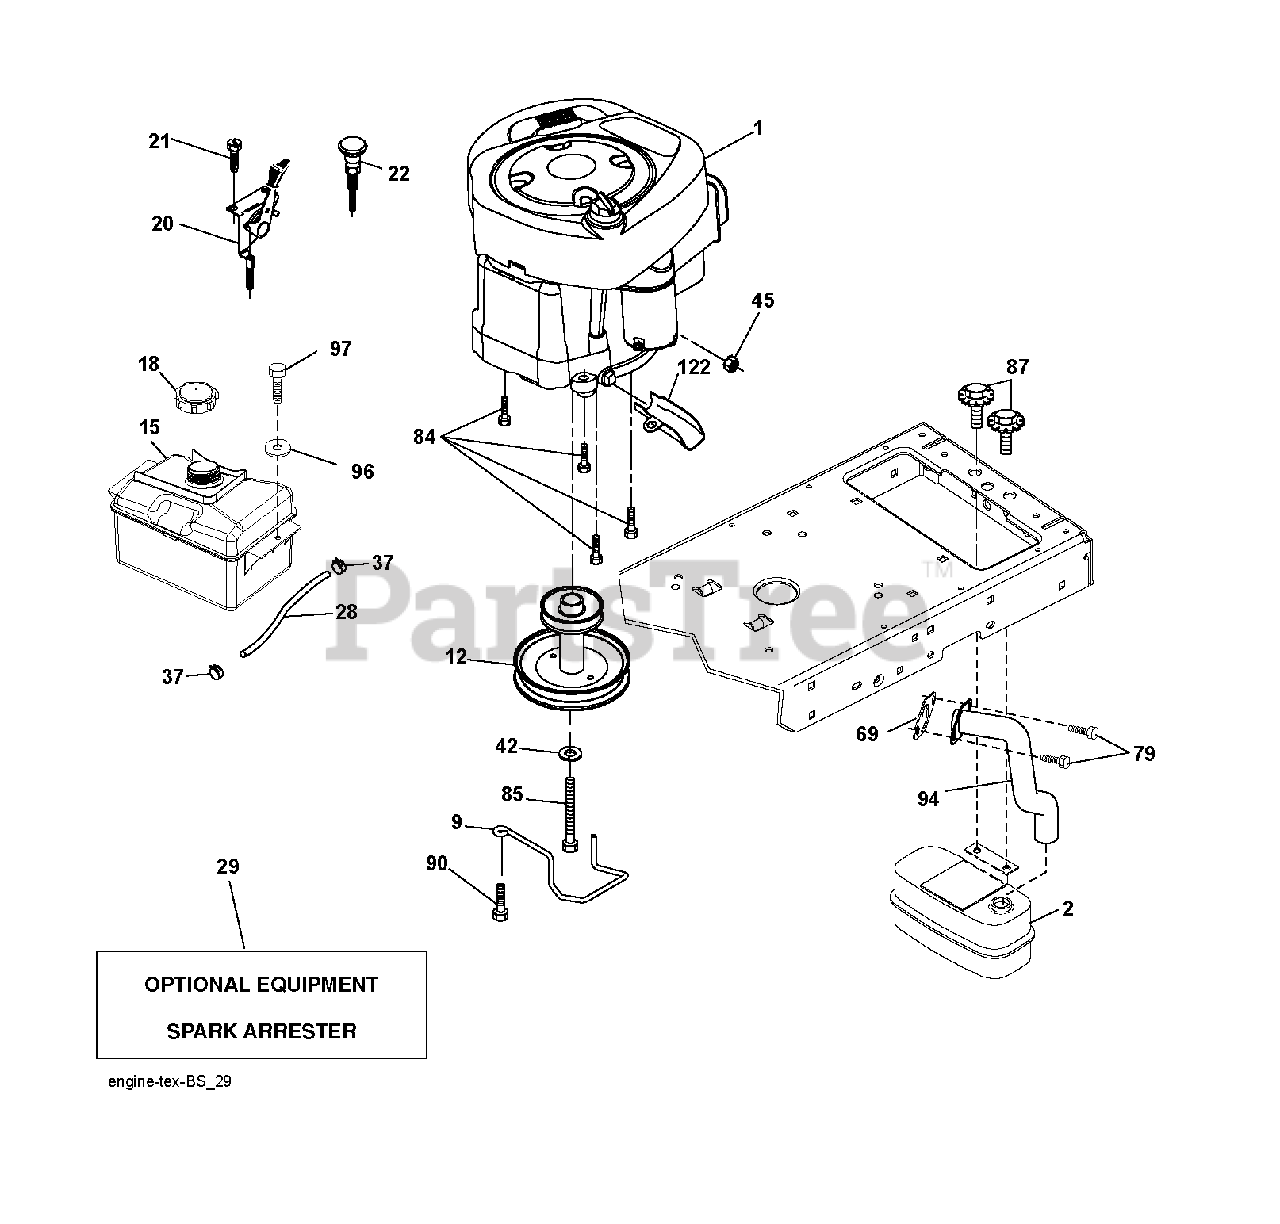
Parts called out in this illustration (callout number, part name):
2	MUFFLER.SINGLE.CYL.KOHL/B&S
9	KEEPER.BELT.ENGINE.4.2
12	PULLY ENGINE
15	TANK FUEL FRT 1.5 GAL
18	CAP.FUEL.2.25"VENTED"
20	CONTROL.TH/CK.C.
21	SCREW.#10 X 0.750.BOS THREAD
28	LINE.FUEL.20
29	ARRESTER SPARK (OPTIONAL)
37	HOSE CLAMP
42	LOCKWASHER
45	NUT
69	REPL BY 532 27 22-93
79	SCREW.SOCKET HD.5/16-1
84	SCREW.3/8-16
85	BOLT HEX 7/16-20X4-1/4"
87	BOLT, 5/16-18 X 1 3/4
90	SCREW 3/8-16X1
94	EXHAUST.TUBE.B&S.
97	SCREW HEXWSHR 1/4-20X3/4
122	EXTENSION DRAIN OIL
